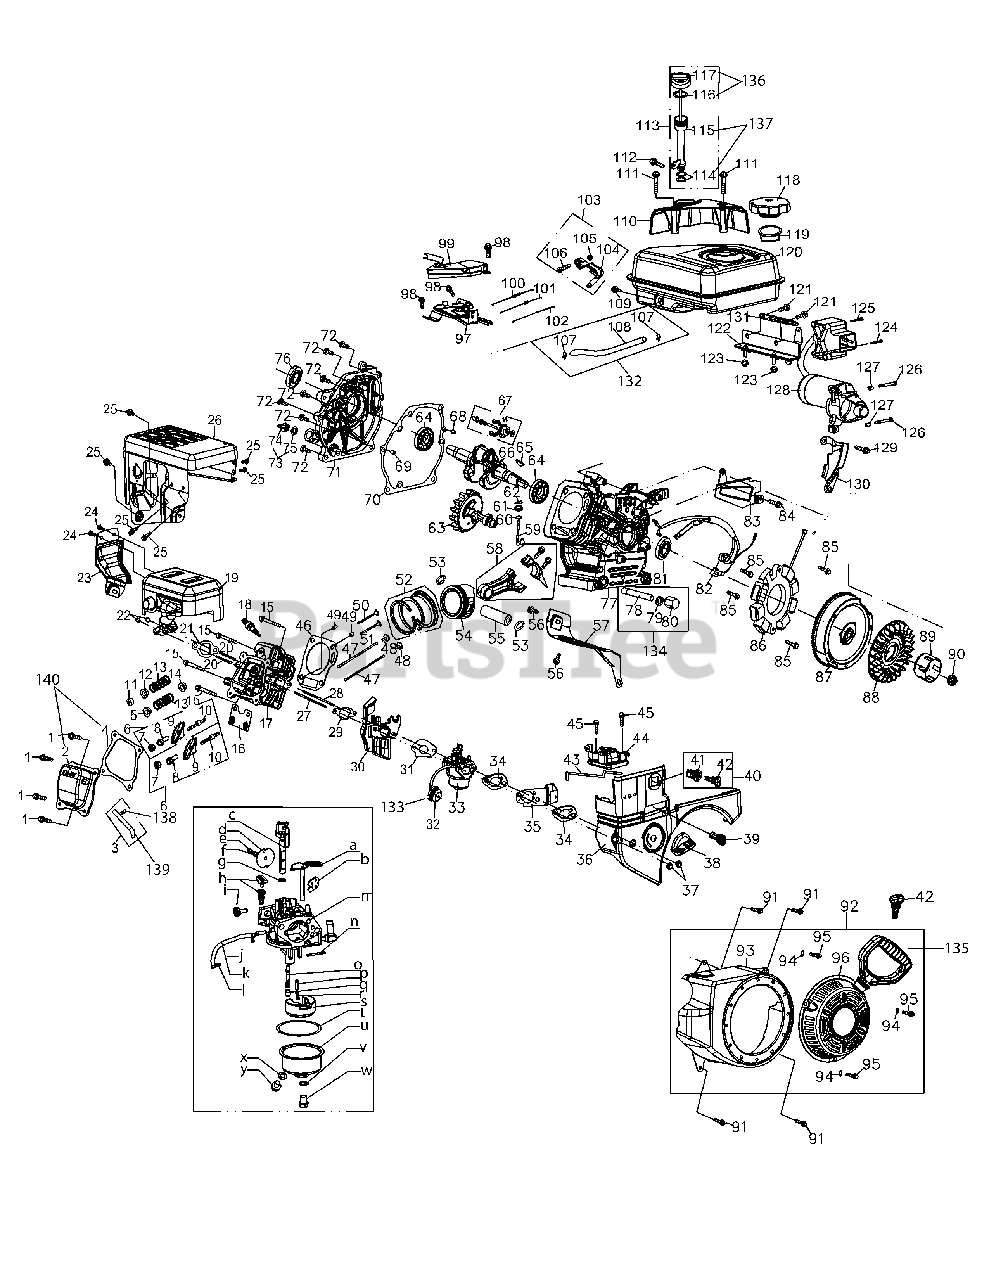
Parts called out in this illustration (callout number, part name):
1	Bolt M6×16
2	Valve Cover
3	Breather Hose Assembly
4	Valve Cover Gasket
5	Intake Valve Spring Retainer
6	Rocker Arm Assembly
7	Nut, Pivot Locking
8	Adjusting Nut ,Valve
9	Rocker Arm
10	Bolt, Pivot
11	Exhaust Valve Adjuster
12	Exhaust Valve Spring Retainer
13	Valve Spring
14	Intake Valve Seal
15	Bolt M8×55
16	Push Rod Guide
17	Cylinder Head
18	Spark Plug
19	Muffler Assembly
20	Stud M8×36
20	Muffler Stud Assembly
21	Exhaust Pipe Gasket
22	Nut, M8
23	Exhaust Pipe Shield
24	Bolt M6×10
25	Bolt M6×12
26	Muffler Shroud
27	Stud M6×117
28	Stud M6×105
29	Carburetor Insulator Gasket
30	Carburetor Insulator
31	Carburetor Gasket
32	Primer Assembly
33	Carburetor Assembly
34	Carburetor Gasket Plate
35	Choke Control Bracket
36	Engine Shroud
38	Choke Knob
39	Throttle Control Knob
40	Ignition Switch
41	Key Switch Base
42	Ignition Key
43	Choke Push Rod
44	Air Filter Heating Pipe Cover
45	Bolt M6×25
46	Gasket, Cylinder Head
47	Push Rod Kit
48	Tappet
49	Dowel Pin 10×16
50	Valve Kit
51	Valve Kit
52	Piston Ring Set
53	Piston Pin Snap Ring
54	Piston
55	Piston Pin
56	Bolt M6×12
57	Air Shield
58	Connecting Rod Assembly
59	Governor Arm Shaft
60	Washer 5.2×1.9
61	Governor Seal
62	Cotter Pin
63	Camshaft Assy.
64	Bearing
65	Flywheel Key
66	Crankshaft Assembly
67	Governor Gear/Shaft Assembly
68	Dowel Pin 7x14
69	Dowel Pin 9x14
70	Crankcase Cover Gasket
71	Cover Comp, Left Crankcase
72	Bolt:M8X32
73	Oil Fill Plug Assembly
74	Fill Plug
75	O-Ring
76	Oil Seal
77	Crankcase
78	Oil Drain Pipe
79	Washer 10×16×1.5
80	Oil Drain Plug
81	Oil Seal 25×41.25×6
82	Ignition Coil
83	Air Flow Shield
84	Bolt M6 x 10
85	Bolt,Flange M6 x 25
86	Stator
87	Flywheel
88	Cooling Fan
89	Starter Cup
90	Nut M14
91	Bolt, M6 x 12
92	Recoil Starter
93	Blower Housing
94	Flat Washer
95	Bolt,Flange M6 x 10
96	Recoil Starter Assembly
97	Throttle Control Assembly
98	Bolt, M6 x 12
99	Governor Shield
100	Governor Spring
101	Throttle Return Spring
102	Governor Rod
103	Governor Arm Assembly
104	Governor Arm Bracket
105	Nut M6
106	BOLT:M6 X 21 GOVN ARM
107	Fuel Hose Clamp
108	Fuel Hose
109	BOLT:M6X12 ZINC COATING
110	Cover - Engine/Dipstick
112	Bolt, M6 x 12
113	Dipstick Assembly Complete
114	O-Ring - Oil Fill Tube
115	Dipstick Tube
116	O-Ring - Dipstick
117	Dipstick Cap
118	Fuel Cap Assembly
119	Fuel Level Indicator
120	Fuel Tank
120	Fuel Tank Nipple
121	Bolt, Flange M6 x 20
122	Switch Hsg Mounting Bracket
123	Bolt, M6
124	Screw M4 x 55
125	Screw M4 x 60
126	Screw M6 x 32
127	Dowel Pin
128	Electric Starter
129	Bolt, M6 x 18
130	Blower Housing Shield
131	Flexible Clamp
132	Fuel Line Kit
133	Primer Bulb
134	Oil Drain Assembly
135	Starter Handle
136	Dipstick Assembly
137	Oil Fill Tube Assembly
139	Breather Hose
140	Valve Cover Kit
